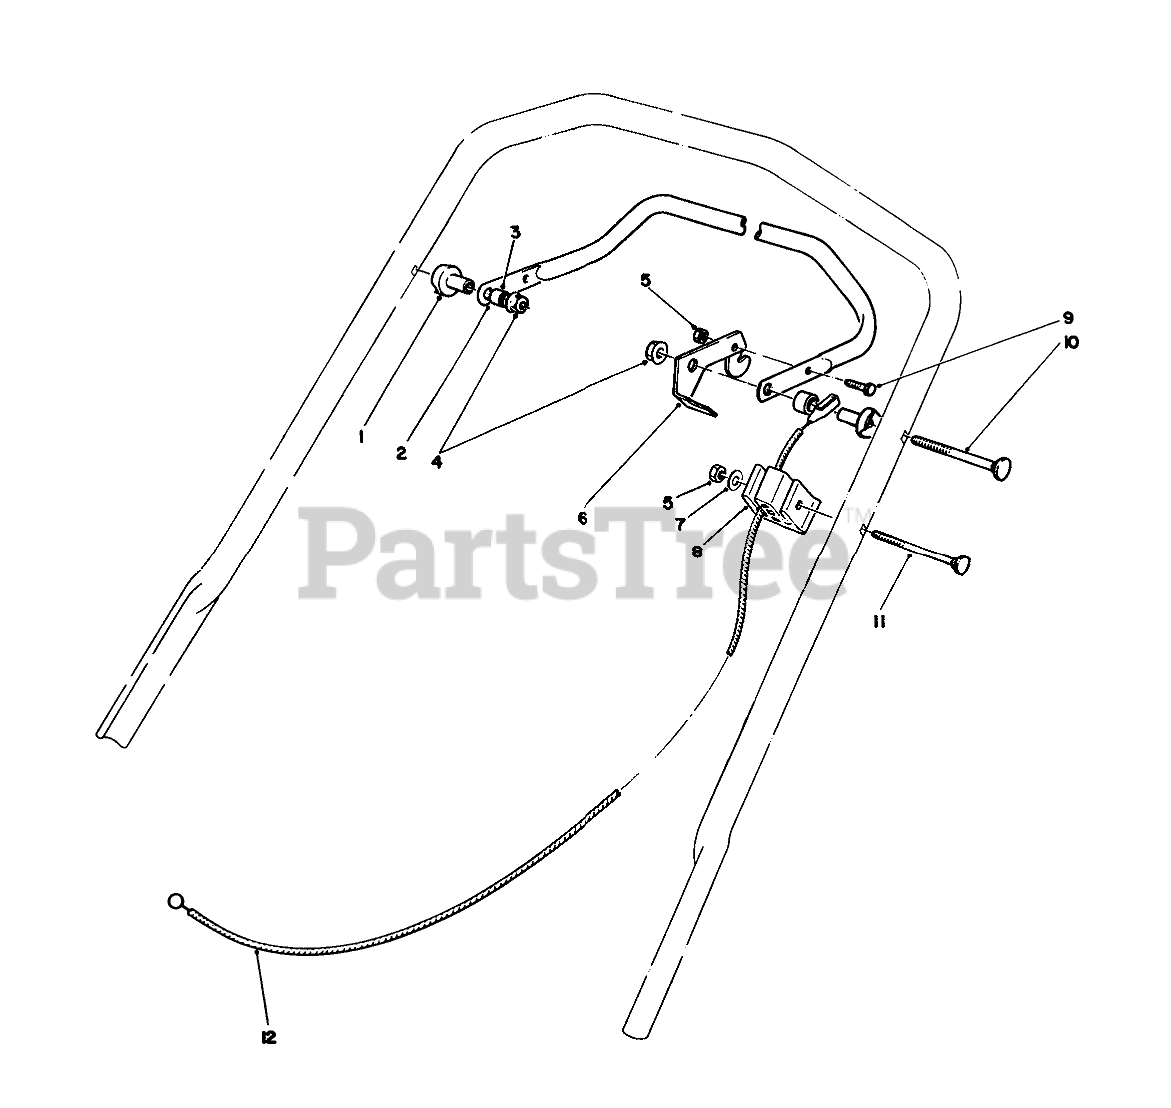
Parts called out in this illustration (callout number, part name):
1	SPACER-SUPPORT
2	Bar-Control
3	SPACER-NYLON
4	NUT-LOCK, NI
5	NUT-LOCK, NI
6	LEVER-CONTROL
7	WASHER-FLAT
8	SUPPORT-CABLE
9	SCREW-HH
10	5/16-18 X 2 HNDLE SCREW
11	HANDLE SCREW
12	BRAKE CABLE
